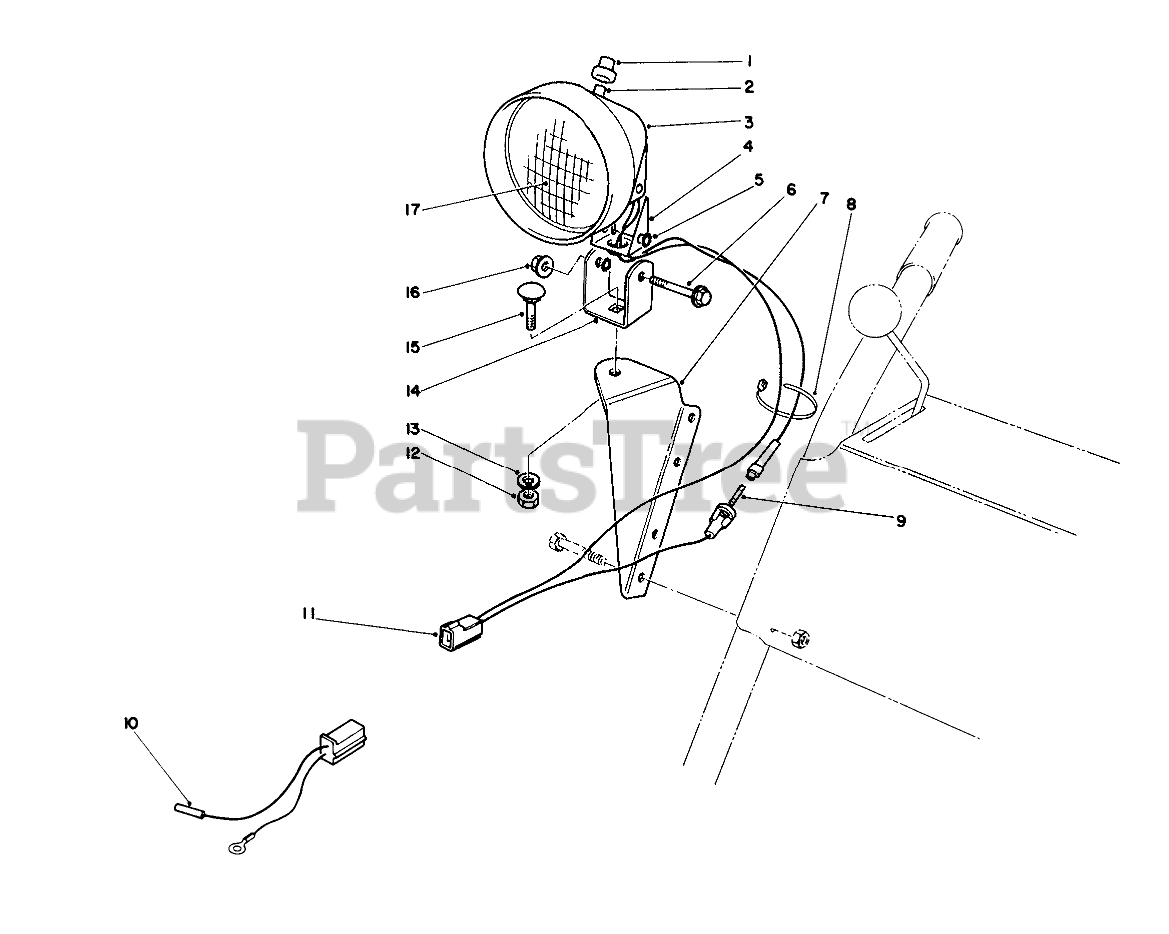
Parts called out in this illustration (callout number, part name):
1	BOOT-SWITCH
2	SWITCH ASM
3	Bucket-Headlamp
4	TO BE DISCONTINED-NOT NEEDED ON PRODUCT
5	WASHER-LOCK
6	SCREW-HH
7	LAMP MOUNT B
8	TIE-CABLE
9	Fuse-7 1/2 Amp
10	WIRE ASM
11	WIRE ASM
12	NUT-HEX
13	WASHER-LOCK
14	BRACKET
15	BOLT-CARR
16	NUT-HF
17	SEALED BEAM
